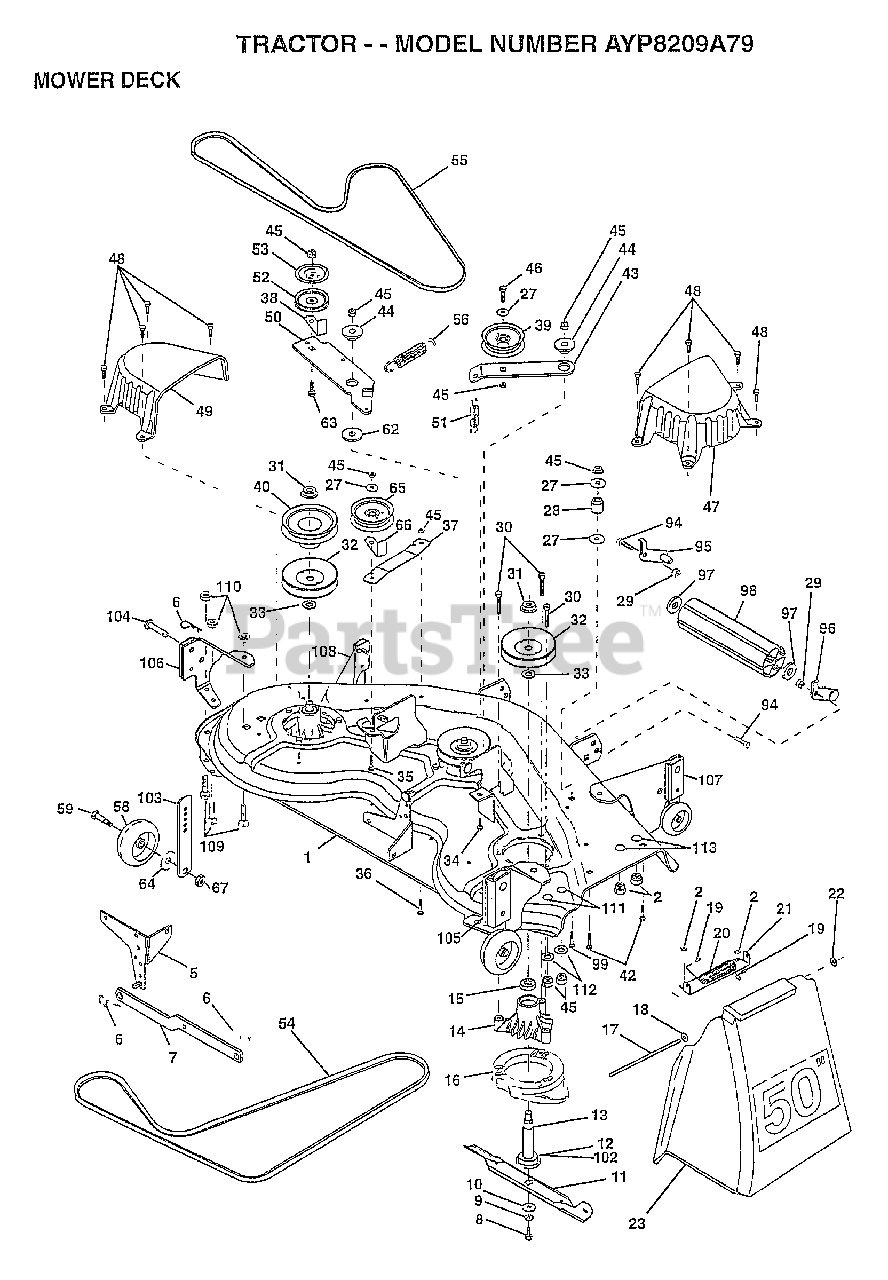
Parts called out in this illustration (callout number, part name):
1	"DECK ASM-50"""
4	RUNNER-LH M
5	BRKT.ASM.SW.44/50
8	BLADE BOLT
10	WASHER.HARD.BLADE
11	"BLADE.50"" HD"
12	BEARING.BALL
13	SHAFT.ASM.W/BRNG
14	HOUSING.MAND.44.V
15	BEARING
16	STRIPPER RND MWR
17	ROD-HINGE T
18	WASHER
19	CAP-SLEEVE LT
20	SPRING TORSION
21	BRKT DEFLECTOR
22	NUT PUSH M
23	DEFLECTOR
24	"RUNNER RH 50"" DK"
25	WASHER M
27	WASHER
29	NUT
32	PULLEY.MANDREL.42
33	WASHER
34	BOLT.3/8-14X1.25
35	BOLT
36	BOLT D
37	STIFFENER.ARM.IDL
38	"KEEPER-BELT,IDLER"
39	FLAT IDLER PULLEY
40	"PULLEY.DRIVEN.44"""
42	BOLT
43	"ARM.IDLER.SEC.44"""
44	SPACER RETAINER
47	"COVER.MAND.RH.44"""
48	SCREW.1/4-20X5/8
49	COVER.MANDREL.LH
50	ARM.IDLER.PRIMARY
51	"SPRING.SEC.44""VEN"
52	PULLEY.IDLER.VGRO
53	SHIELD.IDLER.44.V
54	BELT V PRIM 50
55	BELT-V.SEC.46.KEL
56	SPRING.EXT.DECK.
57	BAR.ASM.GUAGE.WHL
58	WHEEL GAGE DONUT
59	BOLT.SHOULDER
60	PIN.CLEVIS
61	BRACKET.GUAGE.WHL
62	HARDENED WASHER
63	BOLT.3/8-16X1.50
64	WASHER
65	PULLEY IDELR FLAT
66	"KEEPER-BELT,IDLER"
67	LOCKNUT
94	BOLT
97	WASHER
99	BOLT
102	WASHER.FELT.
